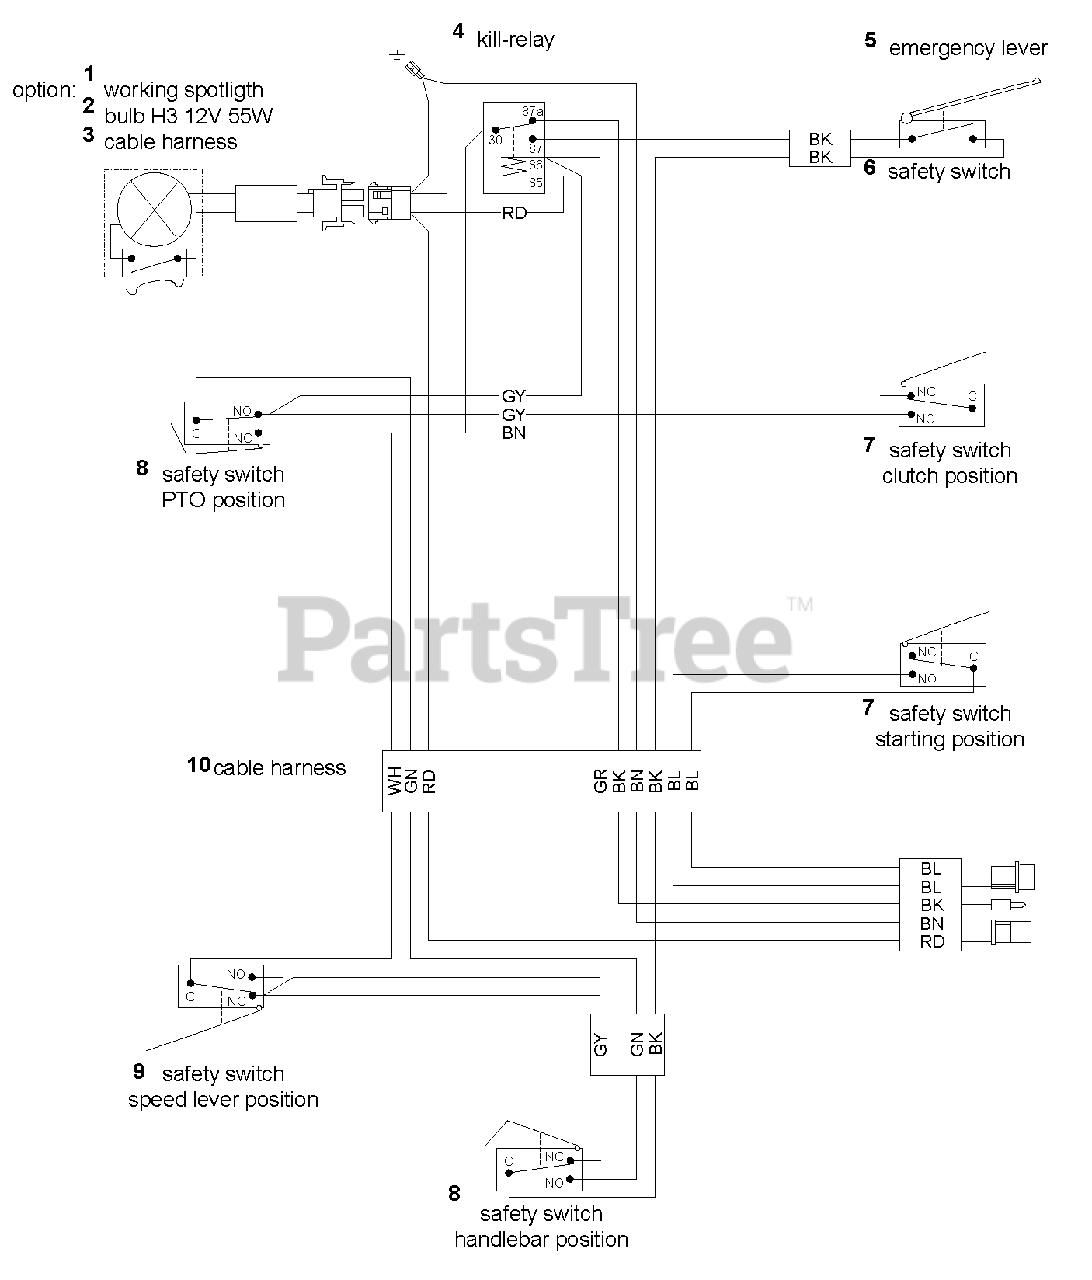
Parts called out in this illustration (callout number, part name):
1	Working Spotlight
2	Bulb H3 12V 55W
3	Wire, Harness
5	Lever, Emergency
7	Safety Switch, Clutch Position
8	Safety Switch, PTO Position
9	Driving, Switch
10	Wiring Harness
